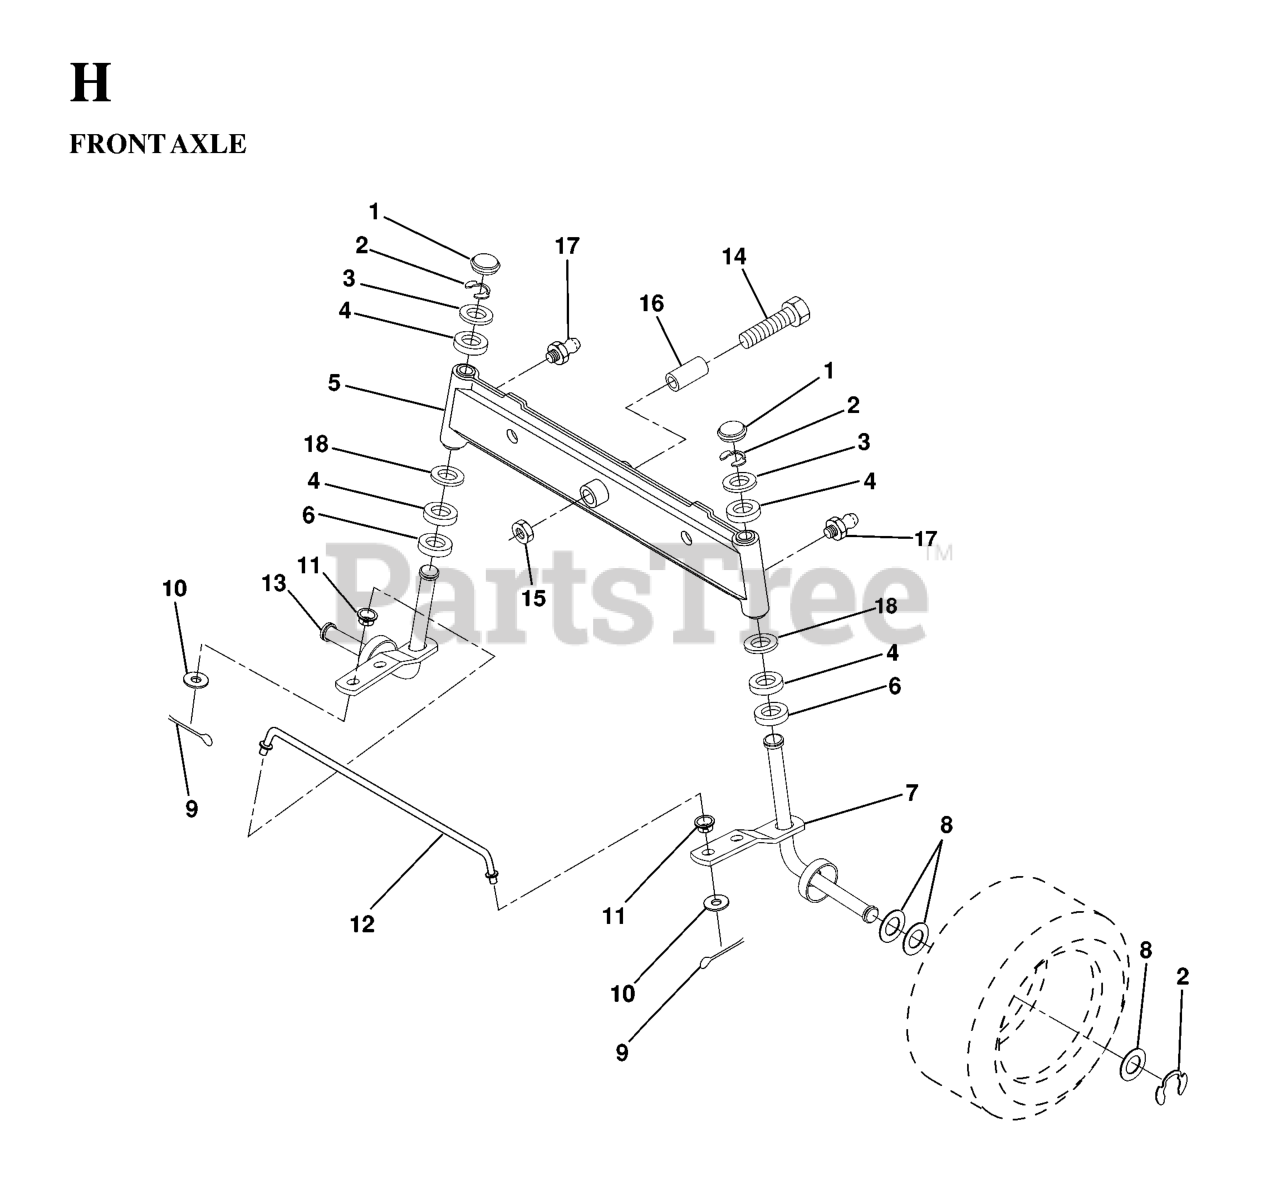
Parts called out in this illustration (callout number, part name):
1	CAP.SPINDLE.BLACK
4	BRNG T
6	THRUST WASHER
7	SPINDLE ASSY RH NLA
9	COTTER PIN
10	WASHER
11	BUSHING.DRAGLINK (2 2)
12	TIE ROD
13	SPINDLE ASSY LH
14	Bolt, Hex Head 5/8-11 x 3-1/2
15	NUT-LOC,FLANGE LT
16	BEARING
17	ZERK M
